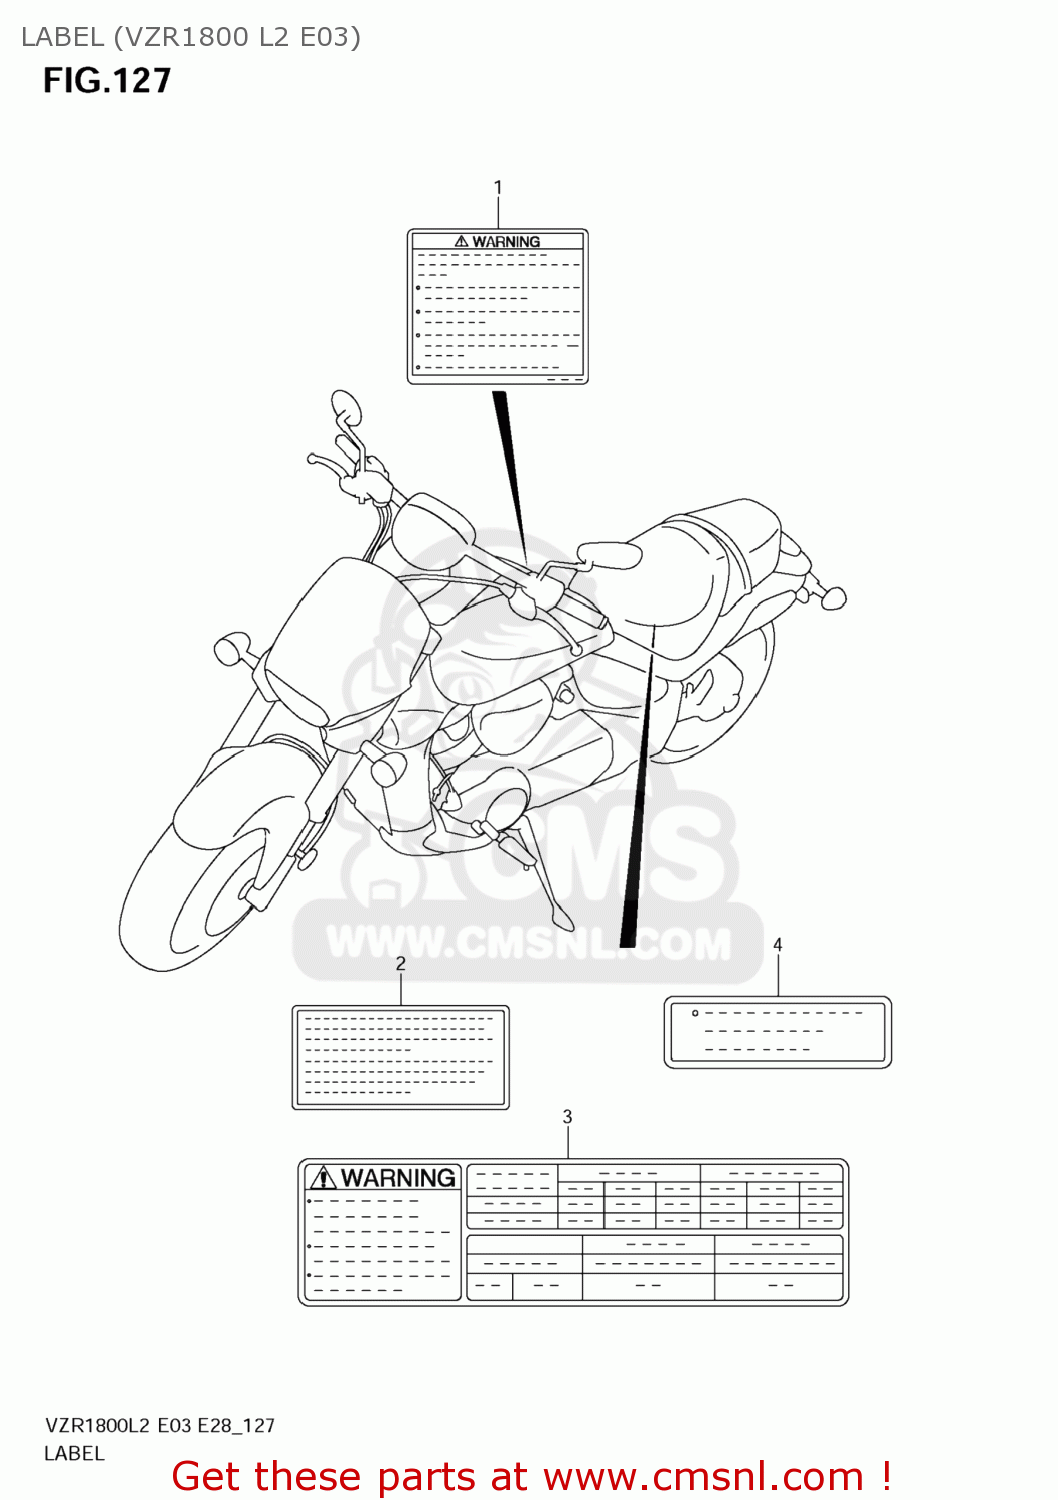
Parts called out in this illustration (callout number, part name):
1	LABEL,GENERAL WARNING
2	LABEL,MANUAL NOTICE
3	LABEL,TIRE INFORMATION
4	LABEL,FUEL INFORMATION
5	MANUAL,OWNER'S
6	MANUAL,SAFETY
